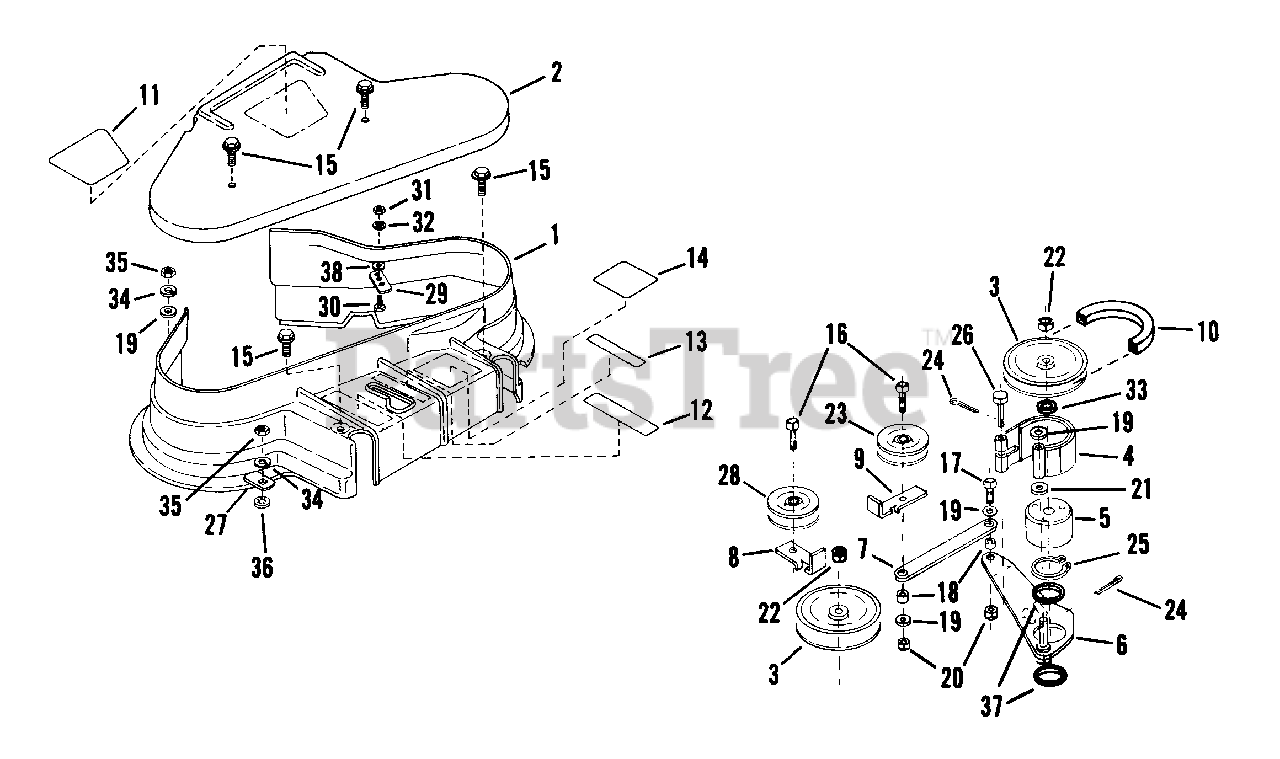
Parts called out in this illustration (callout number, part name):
1	ASSEMBLY, 41" Cover-Bottom & Decal
2	ASSEMBLY, 41" Cover-Top & Decal
3	PULLEY, 5" O.D.
4	BAND, Brake Assembly
5	BRAKE DRUM
6	BRAKE ARM ASSEMBLY
8	GUIDE, Belt
9	RESTRICTOR
10	BELT, AA105
11	DECAL
13	DECAL
15	SCREW, H.H.S.T. 1/4-28x5/8
16	SCREW, H.H.C. 3/8-24x1 3/4
17	SCREW, H.H.C. 3/8-24x3/4
18	SPACER
19	WASHER, 3/8 SAE
20	LOCKNUT, 3/8-24
21	SPACER
22	LOCKNUT, Hex Jam 3/4-16
23	PULLEY, Idler
24	COTTER PIN, 3/32x3/4
25	RING, 2" External Retaining
26	PIN, 1/4 Clevis
27	CLIP
28	PULLEY, Idler
29	GUIDE, Belt
30	SCREW, 1/4-20x1/2 Hex Head Cap
31	NUT, 1/4-20 Hex
32	WASHER, 1/4 Internal Tooth Lock
33	WASHER, 3/4 SAE
34	WASHER, 3/8 Split Lock
35	NUT, 3/8-16 Hex
36	RETAINER, 3/8 Bolt
37	WASHER, 2" I.D.
38	WASHER, 1/4 SAE
